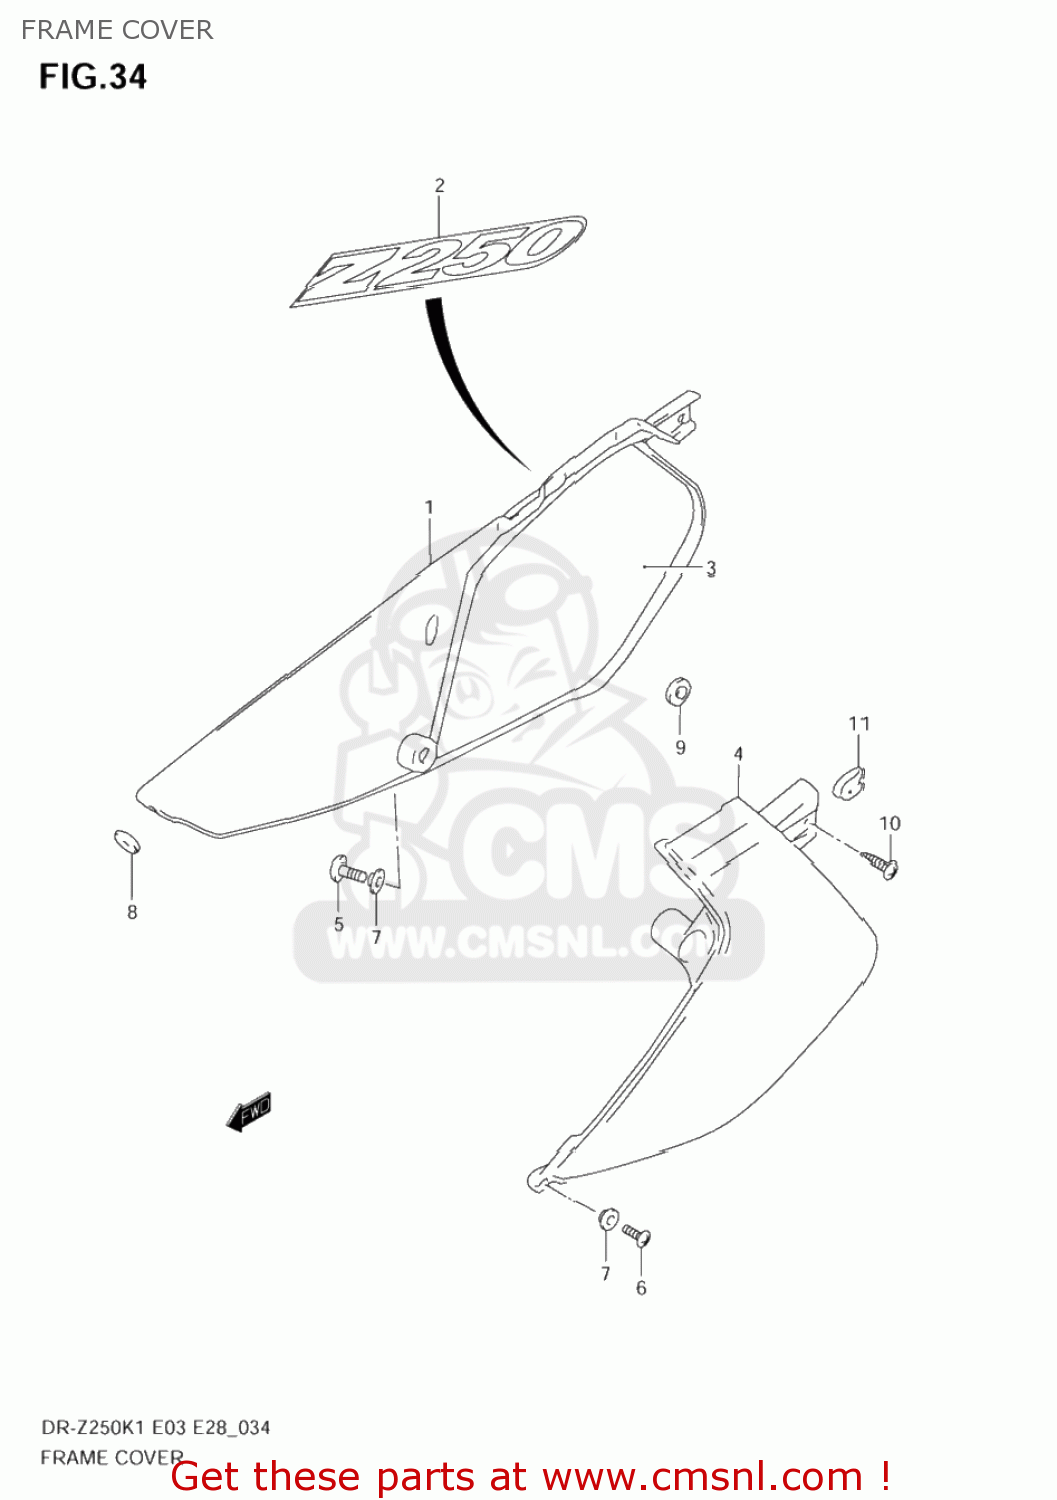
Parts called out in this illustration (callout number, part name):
1	COVER,FRAME,R(WHITE)
2	EMBLEM,FRAME CO
3	SHIELD,FRAME COVER,R
4	COVER,FRAME,L(WHITE)
5	SCREW 6X12
6	SCREW
7	WASHER
8	CUSHION
9	CUSHION
10	SCREW
11	NUT
